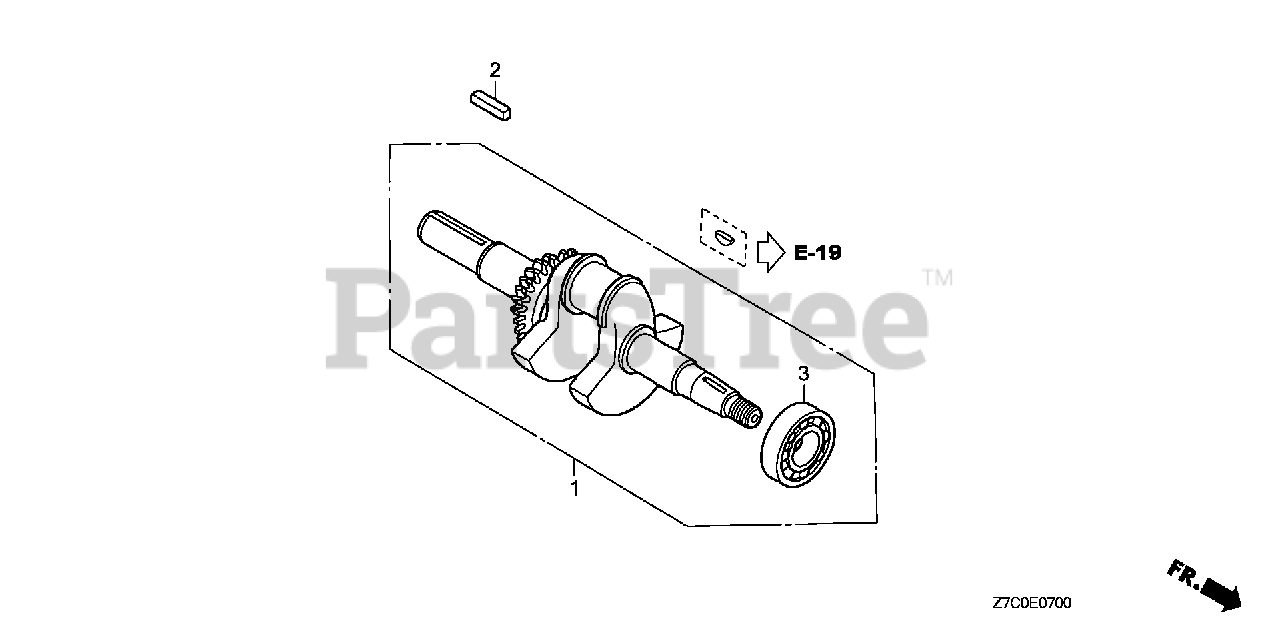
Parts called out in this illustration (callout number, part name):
1	CRANKSHAFT
2	KEY (6.3X6.3X43)
3	BEARING, RADIAL BALL (6206 SH)
